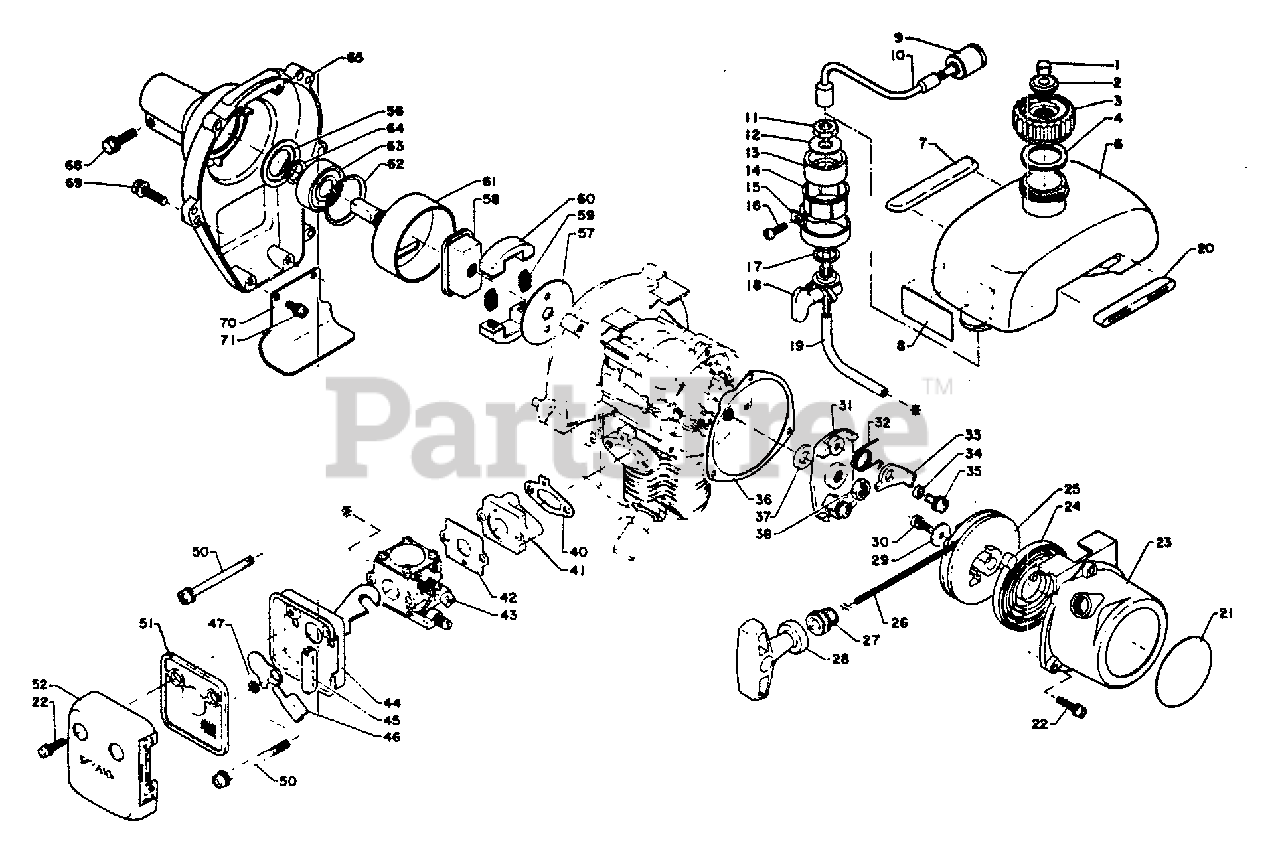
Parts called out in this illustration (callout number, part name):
1	FILTER, CHECK VALVE
2	VENT ASSY
3	CAP, FUEL
6	TANK, FUEL
7	CUSHION
8	LABEL - FUEL VALVE
9	FILTER, FUEL
10	PIPE, FUEL
11	NUT 8×1.25
12	WASHER
14	COLLAR
16	SCREW 4×14
17	GASKET
18	FUEL VALVE ASSY
19	PIPE, FUEL 3×6×85 BLACK
20	CUSHION
21	MODEL PLATE
22	SCREW 4×20
23	CASE, STARTER
24	SPRING, RECOIL
25	REEL, ROPE
26	ROPE, STARTER 3.0×850
27	GUIDE, ROPE
28	GRIP, STARTER
29	WASHER 4.1×15.5×1T
30	SCREW - 4×10
31	PAWL CATCHER
33	RATCHET
34	SPACER 5.2×8×2.1
35	SCREW 5×10
36	GASKET, STARTER
40	GASKET, INTAKE
41	INSULATOR, INTAKE
42	PACKING
43	CARBURETOR
44	CASE, AIR FILTER
46	SHUTTER, CHOKE
47	WASHER 5.2×8×0.8T
50	SCREW 5×57
51	FILTER, AIR
52	COVER, AIR FILTER
56	STOPPER, PIPE
57	PLATE, CLUTCH
58	HUB, CLUTCH
59	SPRING, CLUTCH
60	SHOE, CLUTCH
61	DRUM, CLUTCH
62	RING, SNAP Ø32
63	BEARING, BALL
64	RING, RETAINING - 12
65	CASE, FAN
68	BOLT 5×20
69	SCREW 5×20
70	BRACKET
71	SCREW 4×10
